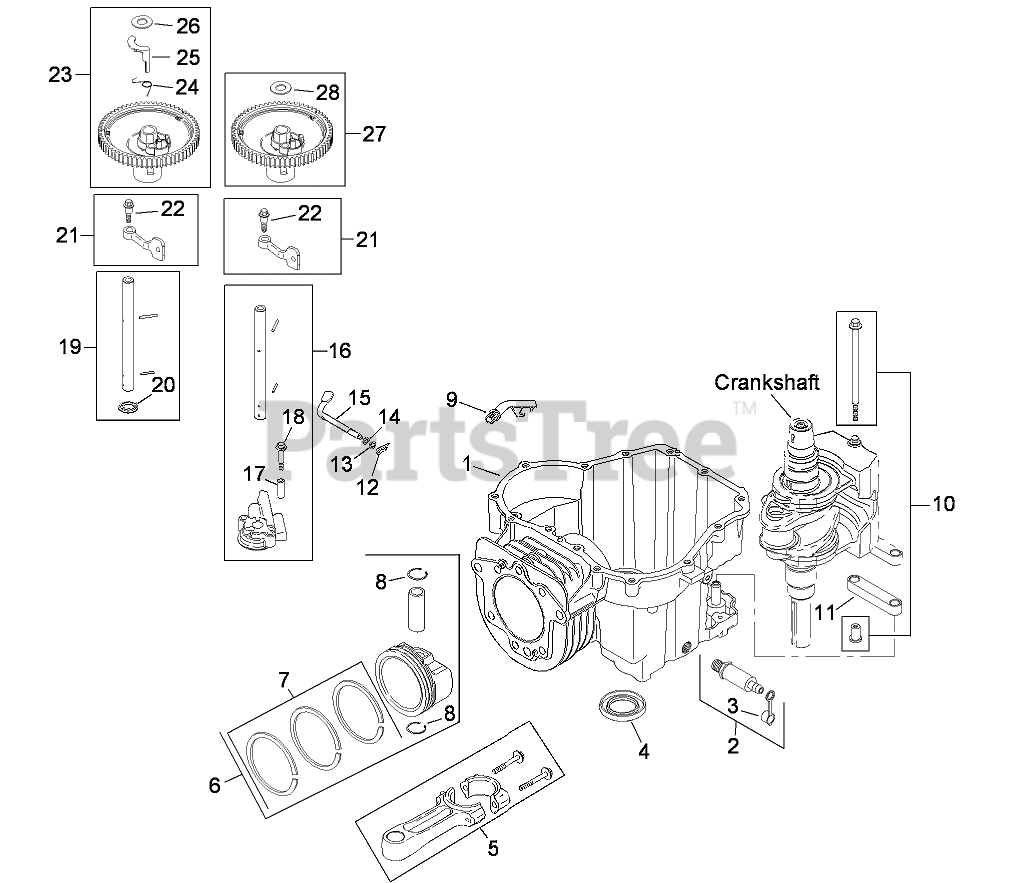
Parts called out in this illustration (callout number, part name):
1	CRANKCASE (SV530/540 SHORT BLOCK)
2	OIL DRAIN VALVE ASM (INCLUDES 3)
3	CAP-VALVE, OIL DRAIN
4	Seal-Oil
5	Connecting Rod ASM
6	Piston and Ring Set (94 mm) (INCLUDES 7, 8)
7	Ring Set (94 mm)
8	Retainer-Pin, Piston
9	Tube-Back, Drain
10	LOCATING PIN ASM
11	LINKAGE-WEIGHT, BALANCE
12	Clip-Pin, Hitch
13	WASHER-FLAT (6mm)
14	WASHER-FLAT (1/4)
15	Shaft-Cross, Governor
16	OIL PUMP ASM (INCLUDES 17, 18)
17	Spacer-Screw, Oil Pump
18	Screw-Pump, Oil
19	CAMSHAFT CENTER ASM (EXHAUST) (INCLUDES 20)
20	WASHER-THRUST
21	Cam Lever ASM (INCLUDES 22)
22	Bolt-Shoulder (M6x1x26)
23	Cam Gear ASM (EXHAUST) (INCLUDES 24-26)
24	Spring-A C R
25	Weight-A C R
26	Washer-Thrust, A C R
27	Cam Gear ASM (INTAKE) (INCLUDES 28)
28	Washer-Thrust, A C R
